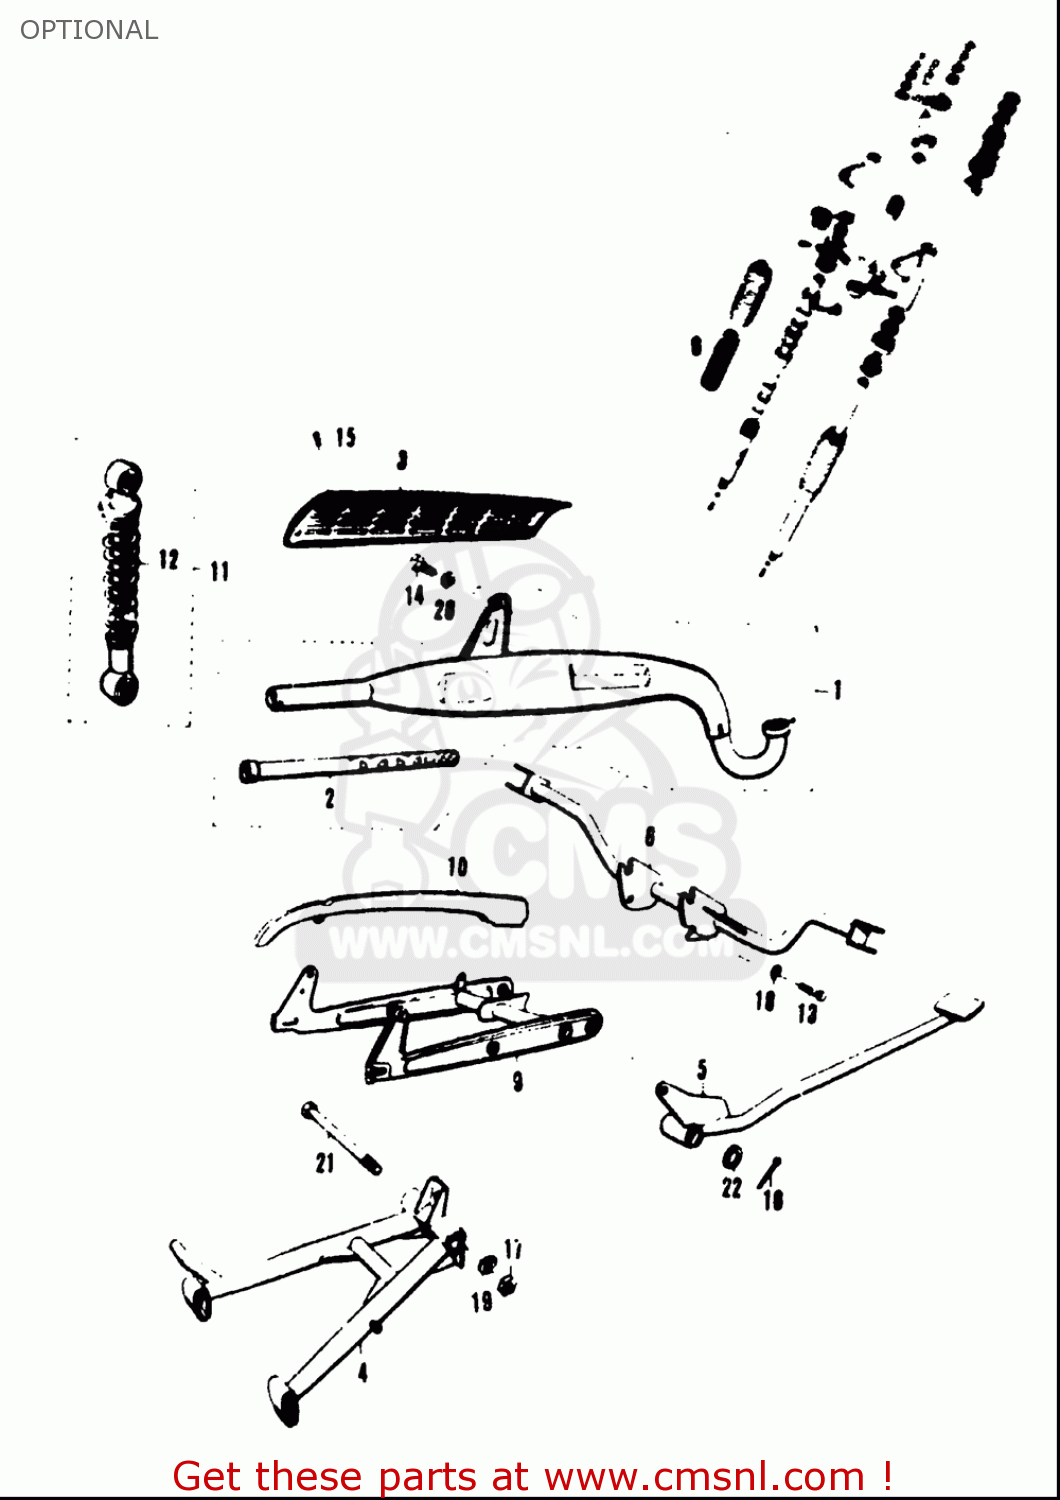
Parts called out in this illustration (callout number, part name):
13	BOLT
14	BOLT
15	SCREW
16	PIN
17	NUT
18	WASHER,LOCK
19	WASHER,LOCK
20	WASHER
21	BOLT
22	WASHER(15.5X26X2.3)
